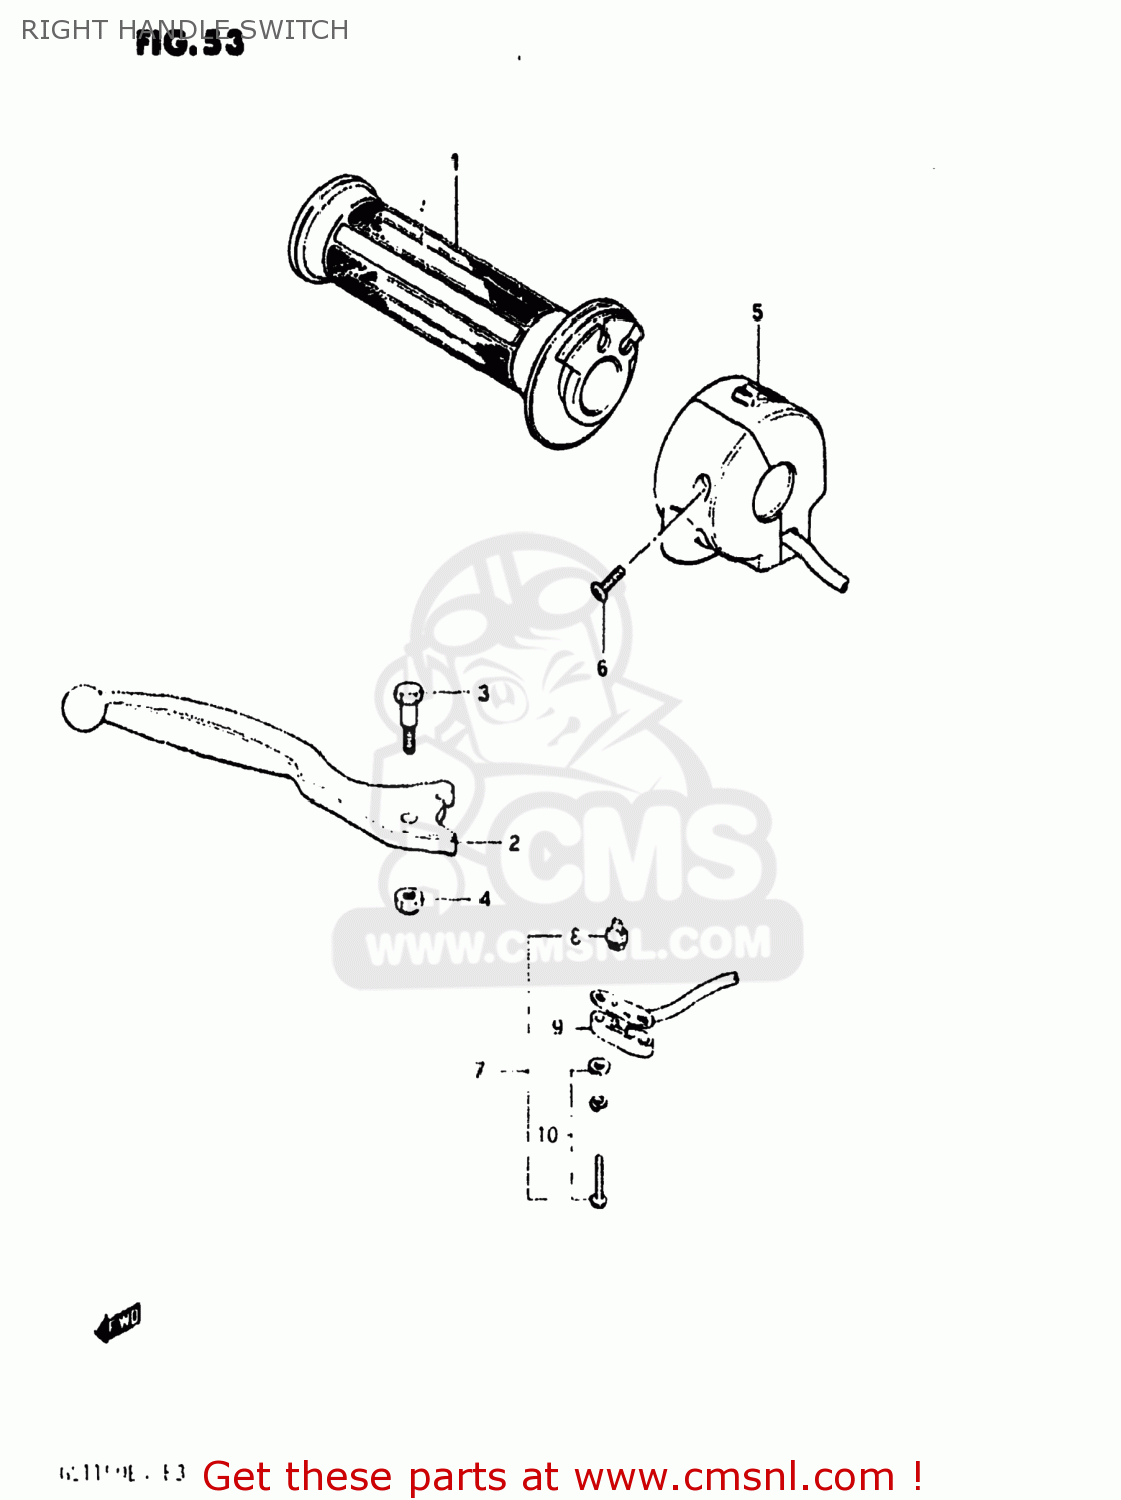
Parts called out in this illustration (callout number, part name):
1	GRIP,THROTTLE
2	LEVER,BRAKE
3	BOLT,LEVER PIVOT
4	NUT 6MM
5	SWITCH ASSEMBLY,HANDLE,RIGHT
6	SCREW
7	SWITCH ASSY,STOP
8	CONTACT,SWITCH
9	COVER,FR BK TERMINAL BASE
10	SCREW
